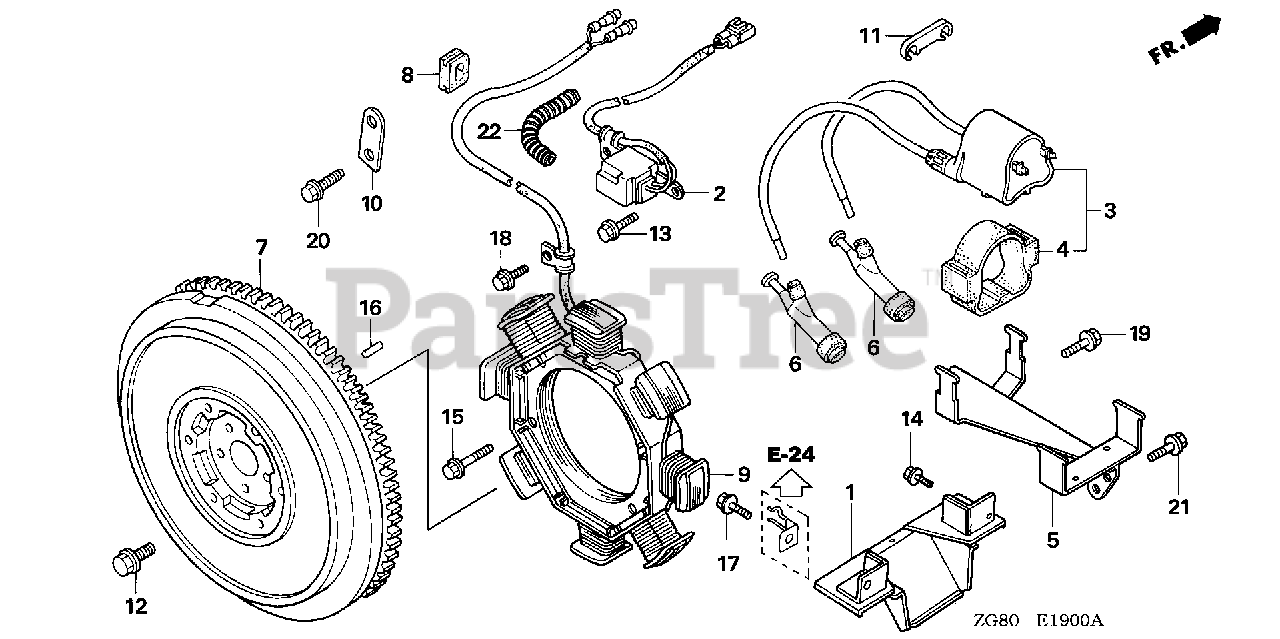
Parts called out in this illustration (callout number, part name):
1	PROTECTOR, HEAT (UPPER)
2	COIL ASSY., PULSER
3	COIL ASSY., IGNITION
4	SUSPENSION, IGNITION COIL
5	BRACKET, ELECTRIC PARTS
6	CAP ASSY., NOISE SUPPRESSOR (NICHIWA Y-EZ RTFM256)
8	GROMMET, WIRE
9	COIL ASSY., CHARGE
10	BRACKET, WIRE HARNESS CLIP
11	CLAMP, WIRE
12	BOLT, HEX. (10MM)
13	BOLT, FLANGE (5X16)
14	BOLT, FLANGE (6X14) (CT200)
15	BOLT, FLANGE (6X28)
16	PIN B, DOWEL (6X10)
17	BOLT, FLANGE (8X20)
18	BOLT, FLANGE (6X14) (CT200)
19	BOLT, FLANGE (6X14) (CT200)
20	BOLT, FLANGE (6X14) (CT200)
21	BOLT, FLANGE (6X14) (CT200)
22	TUBE, CORRUGATE
